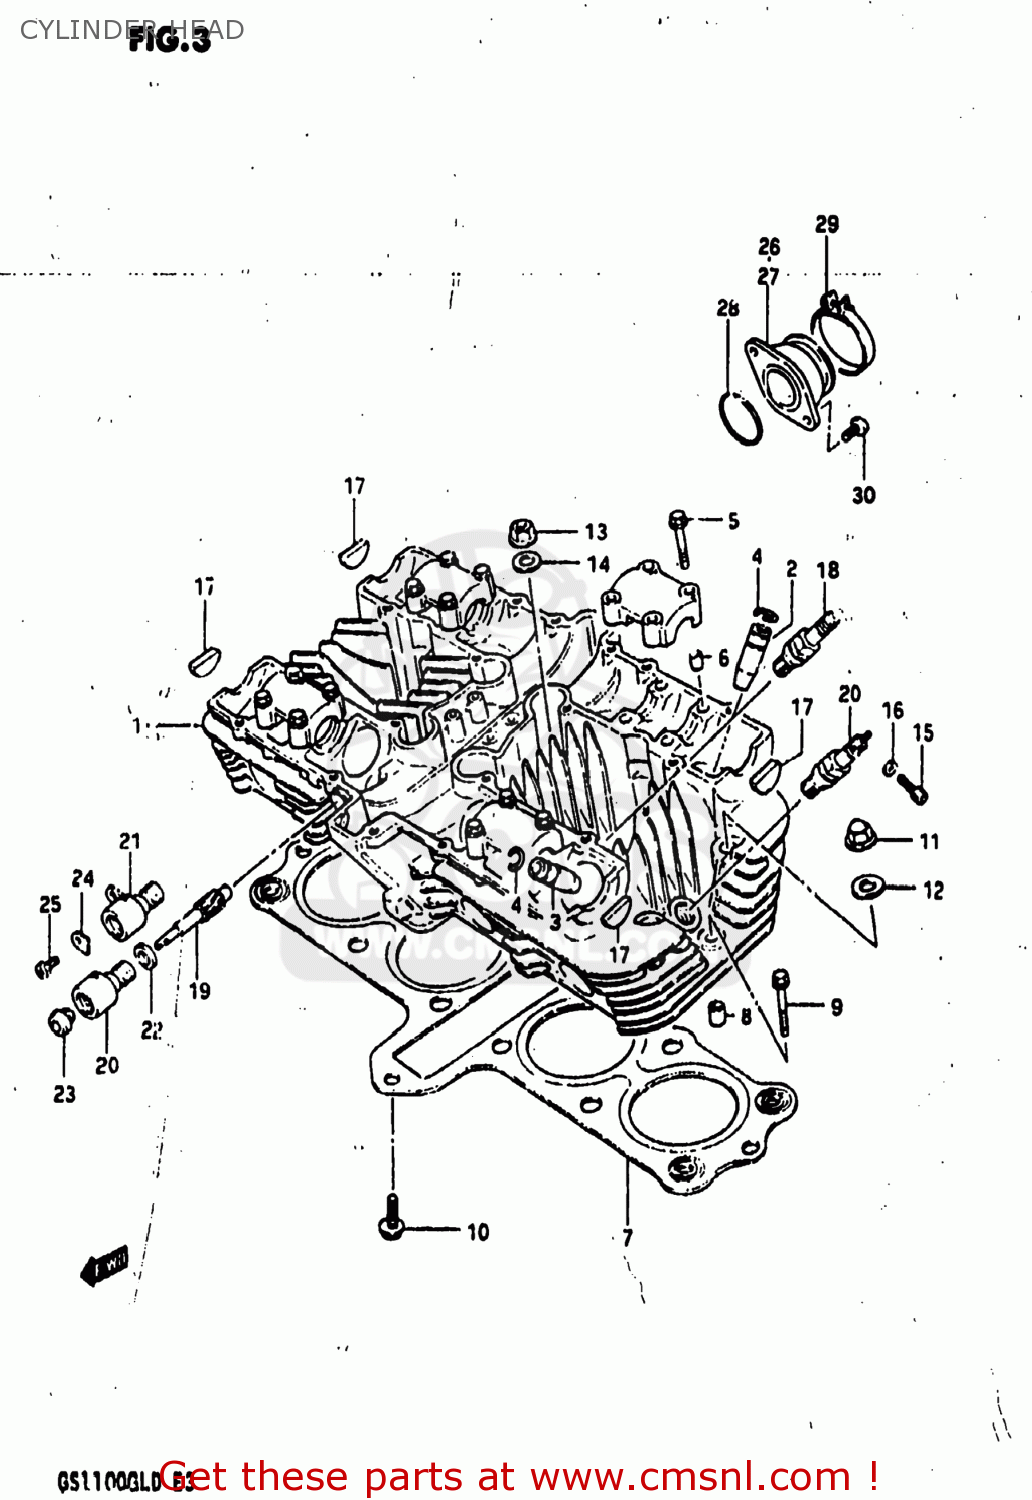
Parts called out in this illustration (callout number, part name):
1	HEAD ASSEMBLY,CYLINDER
2	GUIDE,INTAKE VALVE
3	GUIDE,EXHAUST VALVE
4	RING,SNAP
5	BOLT(6X39)
6	PIN(6.2X8X11)
7	GASKET,CYLINDER HEAD (NAS)
8	PIN
9	BOLT,UNDER
10	BOLT
11	NUT
12	GASKET(10.5X22X2) (NAS)
13	NUT
14	WASHER(10.5X22X2.3)
15	BOLT
16	GASKET(5.3X9.3X1.2) (NAS)
17	PLUG
18	SPARK PLUG
19	GEAR,TACHOMETER DRIVEN
20	SLEEVE,TACHOMETER DRIVE
21	SLEEVE,TACHOMETER DRIVE GEAR
22	SEAL,TACHOMETER DRIVEN
23	SEAL,OIL(5X12X8)
24	PLATE,TACH DRIVE GEAR SLEEVE
25	SCREW(5X12)
26	PIPE,INTAKE,R
27	PIPE,INTAKE,L
28	O-RING (D:2.4 ID:39.7)
29	CLAMP
30	SCREW
